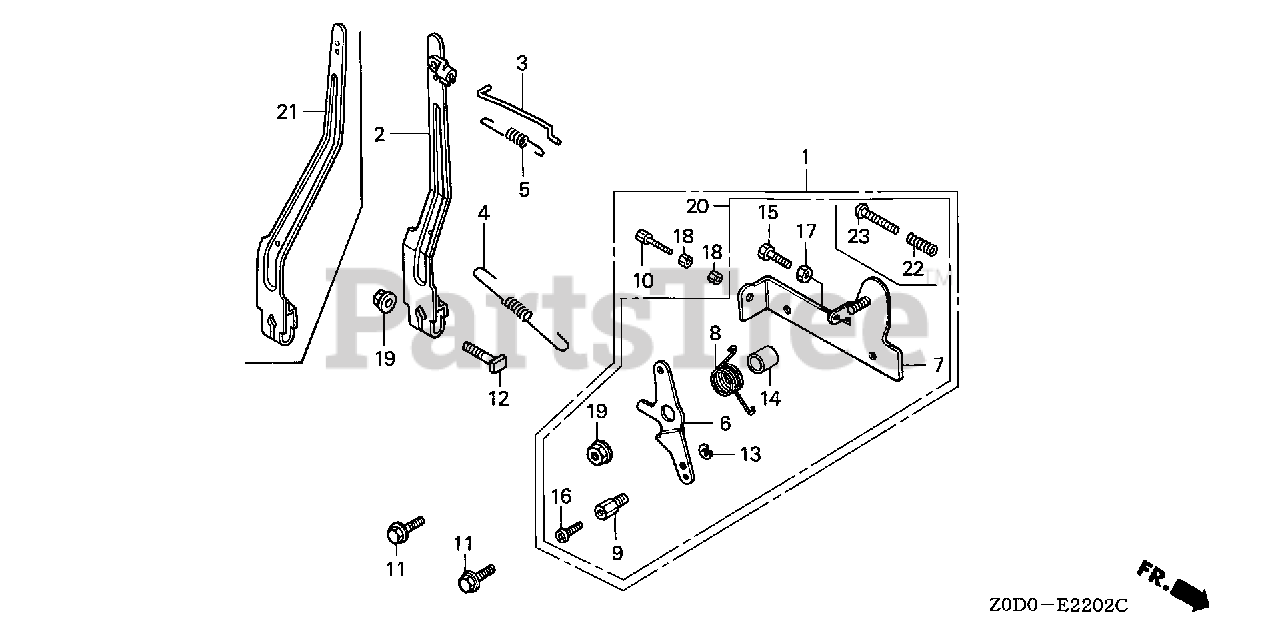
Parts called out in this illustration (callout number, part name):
2	ARM, GOVERNOR
3	ROD, GOVERNOR
4	SPRING, GOVERNOR
5	SPRING, THROTTLE RETURN
6	LEVER, CONTROL (REMOTE)
7	BASE, CONTROL (REMOTE)
8	SPRING, CONTROL LEVER RETURN
9	HOLDER, WIRE
11	BOLT, FLANGE (6X14) (CT200)
12	BOLT, GOVERNOR ARM
13	CIRCLIP (5MM)
14	COLLAR, CONTROL LEVER
15	BOLT, HEX. (5X20)
16	SCREW, PAN (4X6)
17	NUT, HEX. (5MM)
19	NUT, FLANGE (6MM)
20	CONTROL ASSY. (BOMAG)
